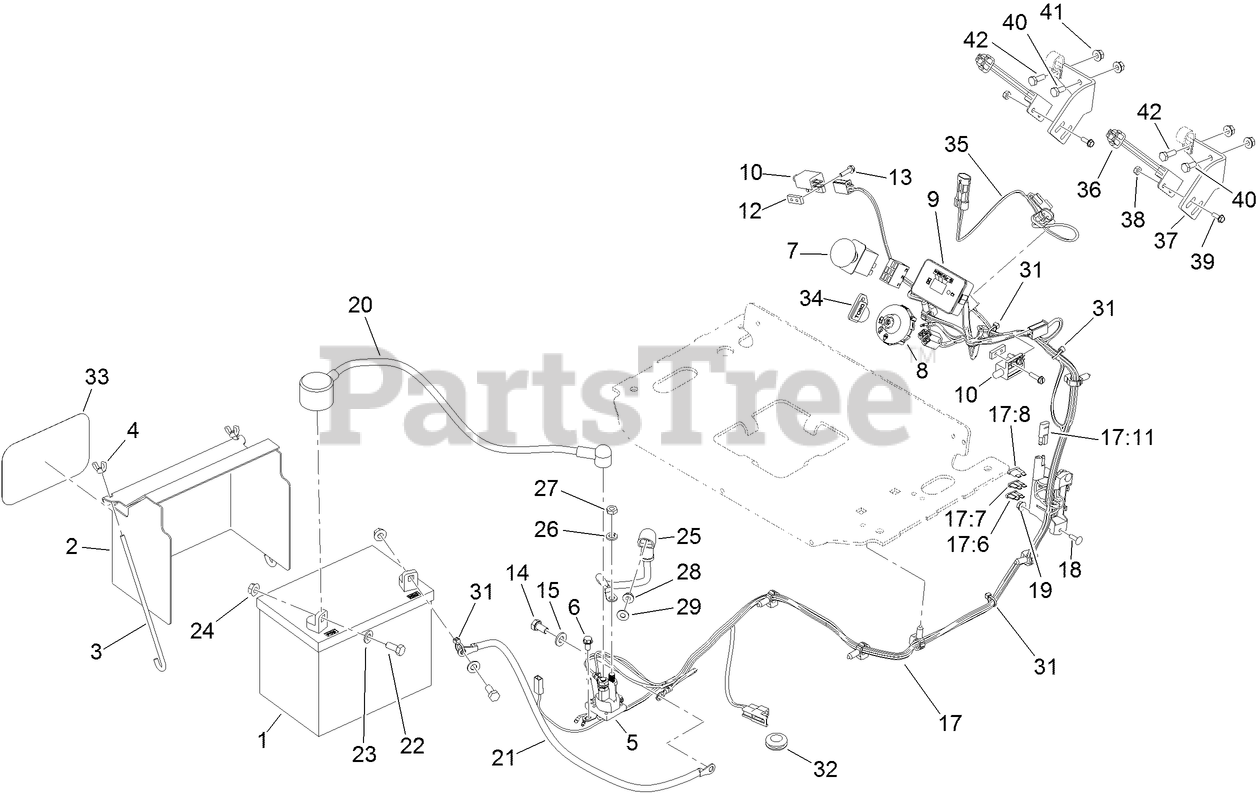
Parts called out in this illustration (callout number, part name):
1	BATTERY-DRY
2	COVER-BATTERY
3	BOLT-HOLDDOWN
4	WINGNUT
5	SOLENOID
6	SCREW-HWH
7	SWITCH-PTO, ON-ON-(ON)
8	SWITCH-IGNITION
9	MODULE-HOUR METER
10	SWITCH-CLOSED, NORMALLY
12	PLATE-TAPPED
13	SCREW-HWH
14	SCREW-HH
15	WASHER-PLAIN
17	HARNESS-WIRING
17:6	FUSE-BLADE, 30 AMP
17:7	FUSE-BLADE, 25 AMP
17:8	FUSE-BLADE, 10 AMP
17:11	CAP-PLUG
18	BOLT-CARR
19	NUT-HF
20	CABLE-BATTERY, POSITIVE
21	CABLE-BATTERY, BLACK
22	SCREW-HH
23	WASHER-PLAIN
24	NUT-HHF, SMOOTH
25	CABLE-BATTERY, RED
26	WASHER-LOCK
27	NUT-JAM
28	NUT-HF
29	WASHER-FLAT
31	TIE-CABLE
32	GROMMET
33	DECAL
34	KEY-IGNITION
35	HARNESS-WIRE, NEUTRAL SWITCH
36	SWITCH-PROXIMITY
37	BRACKET-MOUNT, SWITCH
38	NUT-LOCK, NI
40	SCREW-HH
41	NUT-HHF
42	SCREW-HH
